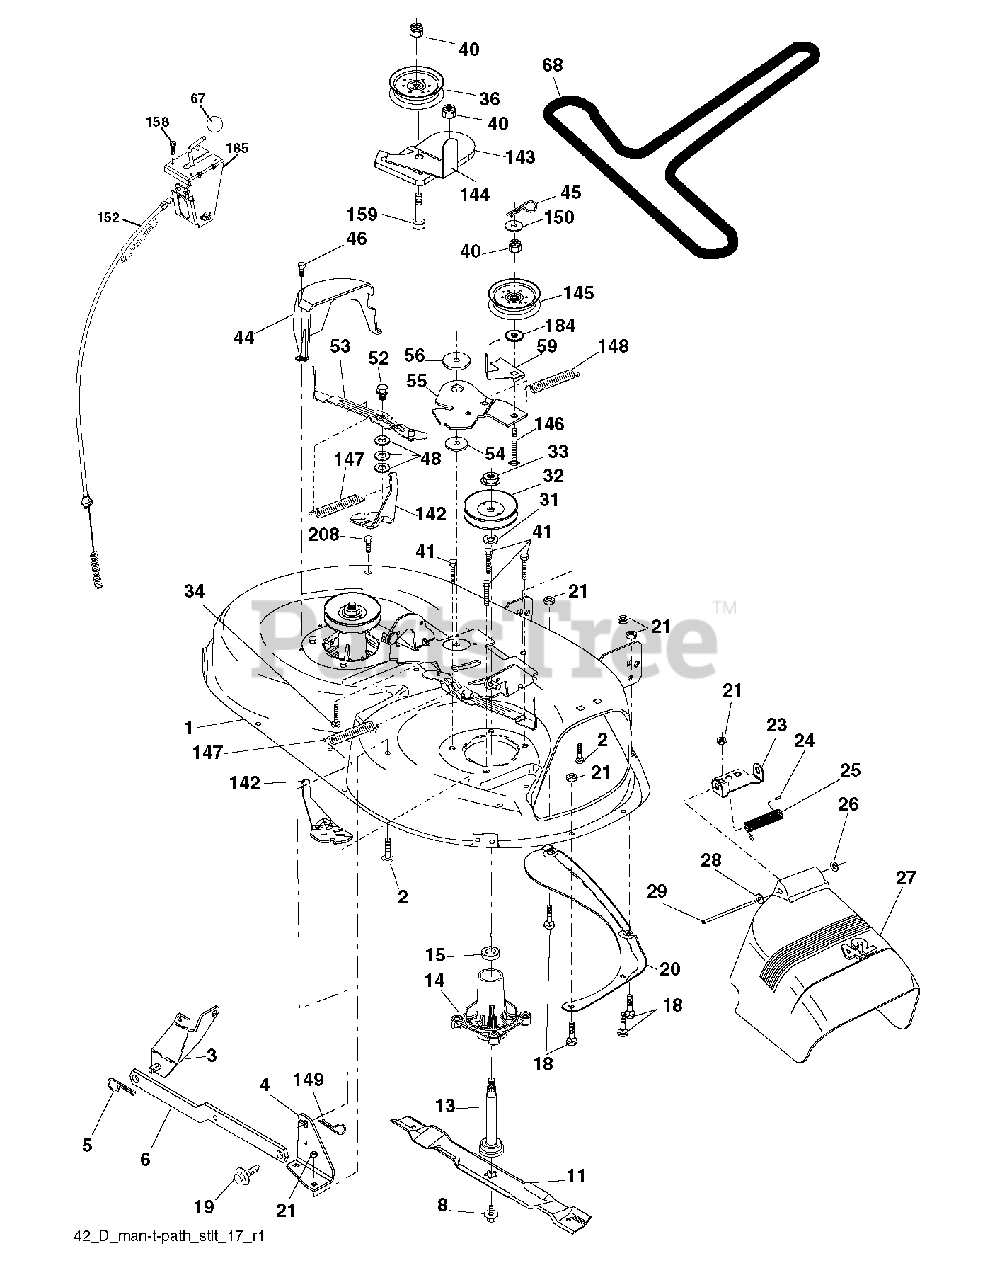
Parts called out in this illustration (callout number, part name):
2	BOLT
3	BRKT ASM SWAY BAR
4	BRACKET SWAY BAR 42" DECK
5	RETAINER-SPRNG RB
6	BAR SWAY DECK
8	BOLT.WASHER.ASM.7/16-2
11	42" HI-LIFT BLADE
13	SHAFT.ASM.MDRL.N/GREASE.38
14	HOUSING.MANDREL.4PT.
18	BOLT
19	BOLT SHD 5/16-18
20	BAFFLE.VORTEX
21	LOCKNUT
23	BRKT, DEFL. MOWER
24	CAP-SLEEVE LT
25	SPRING TORSION
26	NUT PUSH M
27	SHIELD DEFLECTOR
28	WASHER
29	ROD.HINGE
31	WASHER.SPACER.MANDREL
32	PULLEY/MANDREL
33	NUT.FLANGE.LOCK.TOP
34	BOLT.3/8-16X1.50
36	FLAT IDLER PULLEY
40	NUT LOCK FLG 3/8-16 UNC
41	Hex Washer Head Bolt, .313-18 X 1.19
44	GUARD MANDREL LH BLACK
46	SCREW.1/4-20X5/8
52	BOLT.SHOULDER.5/16-18
53	ARM BRAKE ASSY
55	ARM IDLER 42" MOWER LT/YT
56	SPACER.RETAINER.MOWER
59	GUARD, BELT
67	KNOB T (3/8 HOLE)
68	BELT V SECONDARY
142	ANCHOR SPRING BRAKE MOWER
143	BRACKET, ARM IDLER
144	KEEPER.BELT.42".CLUTCH.CABLE
145	PULLEY
146	BOLT, CARRIAGE IDLER BLACK
147	SPRING EXTENSION
148	IDLER RETURN SPRING
149	SPRING.RETAINER.YELLOW.ZINC
150	WASHER LT
152	Clutch Cable Kit
158	SCREW
159	BOLT
184	WASHER
185	HEAD ASM. CABLE CLUTCH
208	SCREW 3/8-16X1/2
